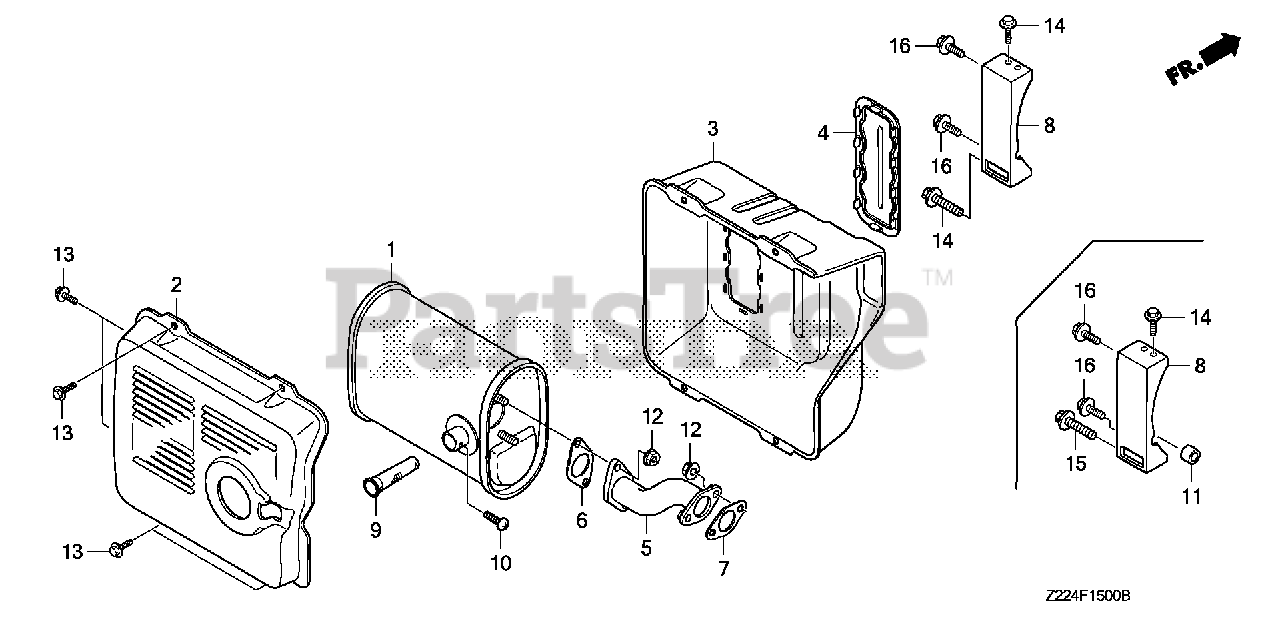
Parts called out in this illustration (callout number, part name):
1	MUFFLER
2	PROTECTOR, MUFFLER (OUTER) *NH105* (MAT BLACK)
3	PROTECTOR, MUFFLER (INNER) *NH105* (MAT BLACK)
4	SEAL, MUFFLER PROTECTOR
6	GASKET, EX. PIPE
7	GASKET, EX. PIPE Use up to Engine SN 2949254.
7	GASKET, EX. PIPE (WACKER)
8	STAY, MUFFLER
9	ARRESTER, SPARK
10	SCREW, TAPPING (4X8)
12	NUT, FLANGE (8MM)
13	BOLT, FLANGE (6X10)
14	BOLT, FLANGE (8X16) Use from Engine SN 1000016.
14	BOLT, FLANGE (8X16)
16	BOLT, FLANGE (8X16)
